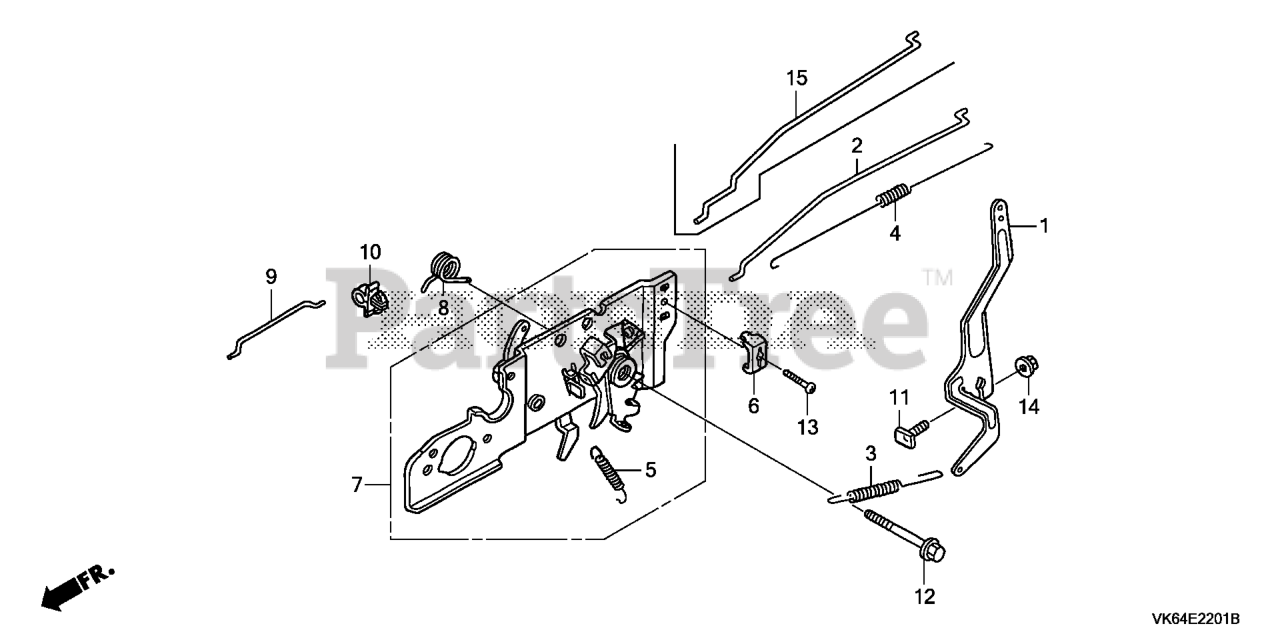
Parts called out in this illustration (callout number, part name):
1	ARM, GOVERNOR
3	SPRING, GOVERNOR
4	SPRING, THROTTLE RETURN
5	SPRING, LEVER
6	HOLDER, CABLE
7	BASE, CONTROL
8	SPRING, CONTROL LEVER RETURN
9	ROD, CHOKE
10	HOLDER, WIRE (FASTEX)
11	BOLT, GOVERNOR ARM
12	BOLT, FLANGE (6X45) (CT200)
12	BOLT, FLANGE (6X50)
12	BOLT, FLANGE (6X45)
13	SCREW, PAN (5X16)
14	NUT, FLANGE (6MM)
15	ROD, GOVERNOR
